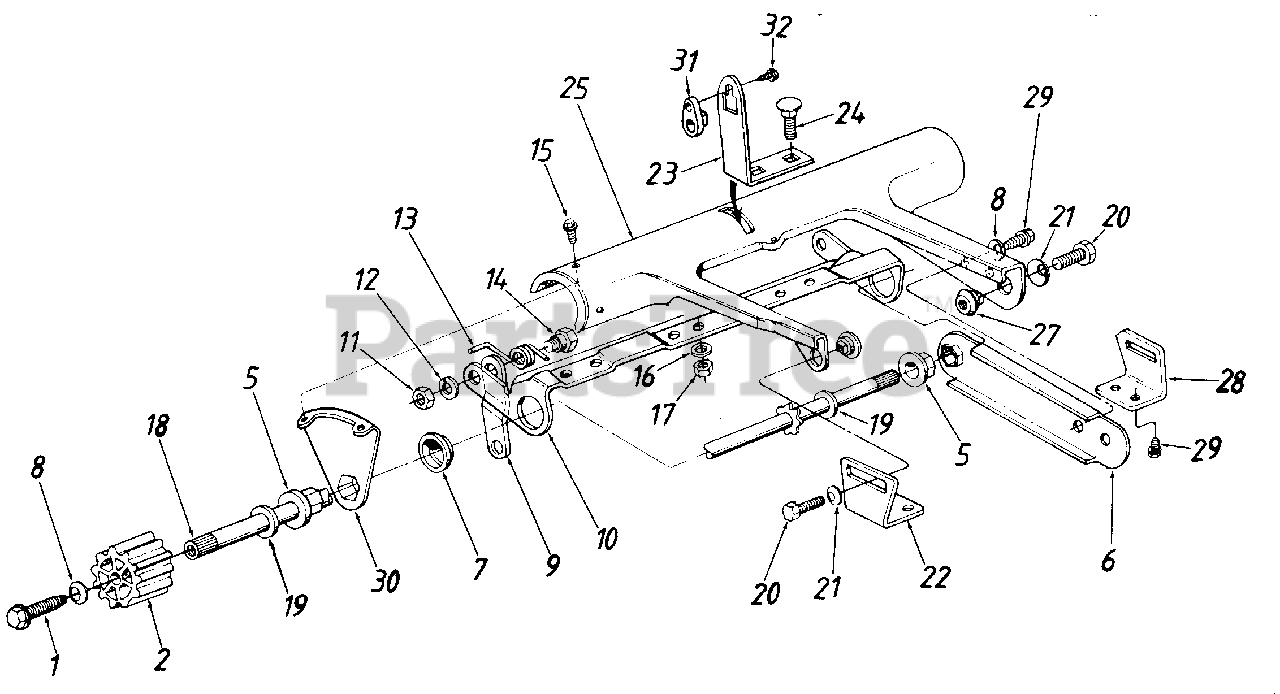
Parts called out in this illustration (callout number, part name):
1	Hex Wash. Hd. Tap Scr. 1/4 -20 x .75" Lg .
2	Wheel Drive Pinion
5	Hex Flange Brg. .504" I.D.
8	Bell-Wash. .265" I.D. x .75" O.D.
11	Hex Nut 5/16-18 Thd.*
12	L-Wash. 5/16" I.D.*
13	Torsion Spring-R.H.
14	Shoulder Bolt .437" Dia.
15	Hex L-Hd. AB-Tap Scr. 1/4" x .62" Lg.
16	L-Wash. 1/4" I.D.*
17	Hex Nut 1/4-20 Thd.*
18	Drive Shaft Ass'y.
19	Fl-Wash. .531" I.D. x .93" O.D.
20	Hex Bolt 5/16-18 x 5/8" Lg.*
21	Bell-Wash. .345" I.D. x .88" O.D.
22	Pivot Bracket-R.H.
28	Pivot Bracket-L.H.
29	Hex Wash. Hd. AB-Tap Scr. 1/4 x .62" Lg.
32	Hex B-Tap Scr. #10 x .44" Lg.
